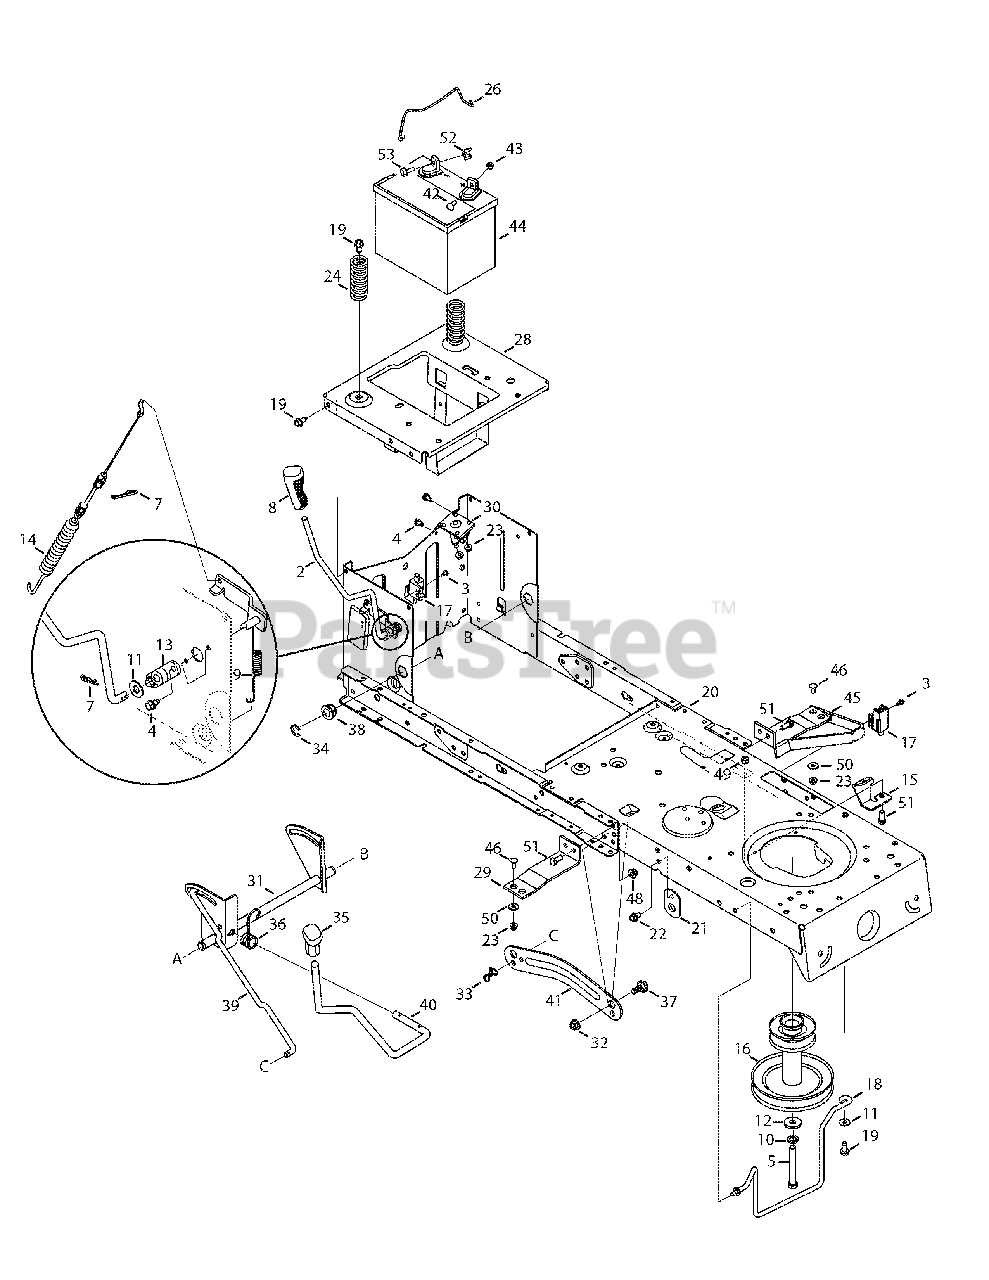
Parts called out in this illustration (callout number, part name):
3	Shoulder Scr #10-16 x .50" Lg.
4	Hex Wash S-Tapp Scr 1/4-20 x .50
5	Hex Hd. Cap Scr. 7/16-20 x 3.25 Gr. 5
7	Hairpin Cotter
8	Handle Grip 3/8
9	Extension Spring
10	Lockwasher 7/16 ID
11	Flat Washer .385 ID x .87 OD x .06
12	Flat Washer .450 x 1.25 x .164
13	PTO Bearing
14	Deck Engagement Cable
16	Engine Pulley 3.39 x 6.12 dia.
17	Interlock Switch
18	Belt Keeper Rod (38" Deck)
19	S-Tapp Scr 5/16-18 x .75
22	Hex Wash HD TT Scr 5/16-18 x .625
23	Hex L-Flanged Nut 1/4-20 Gr. F, Nylon
24	Compression Spring 1.28 x 3.125
25	Lift Bracket
30	Solenoid
32	Flange Lock-Nut 3/8-16 Gr. F, Nylon
33	Cotter Pin .08 x 1.56 Intern - R.H.
33	Cotter Pin .08 x 1.25 Intern - LH
34	"E" Ring .625 Dia.
36	Torsion Spring
37	Shoulder Screw .625 x .175, 3/8-16
38	Hex Flange Bearing .630 ID
40	Deck Lift Handle
42	Carriage Bolt 1/4-10 x .75 Gr. 5
43	Sems Hex Nut 1/4-20
44	Battery 245 CCA (Dry)
46	Carriage Bolt 1/4-20 x .62
47	Screw, 5/16-18 x .625
48	Hex L-Flg Nut 5/16-18 Gr. F, Nylon
49	Hex L-Nut 5/16-18
50	Flat Washer .28 x .74 x .063
51	Hex Screw 5/16-18 x .75
53	Shoulder Screw .25 x .15: 1/4-20
